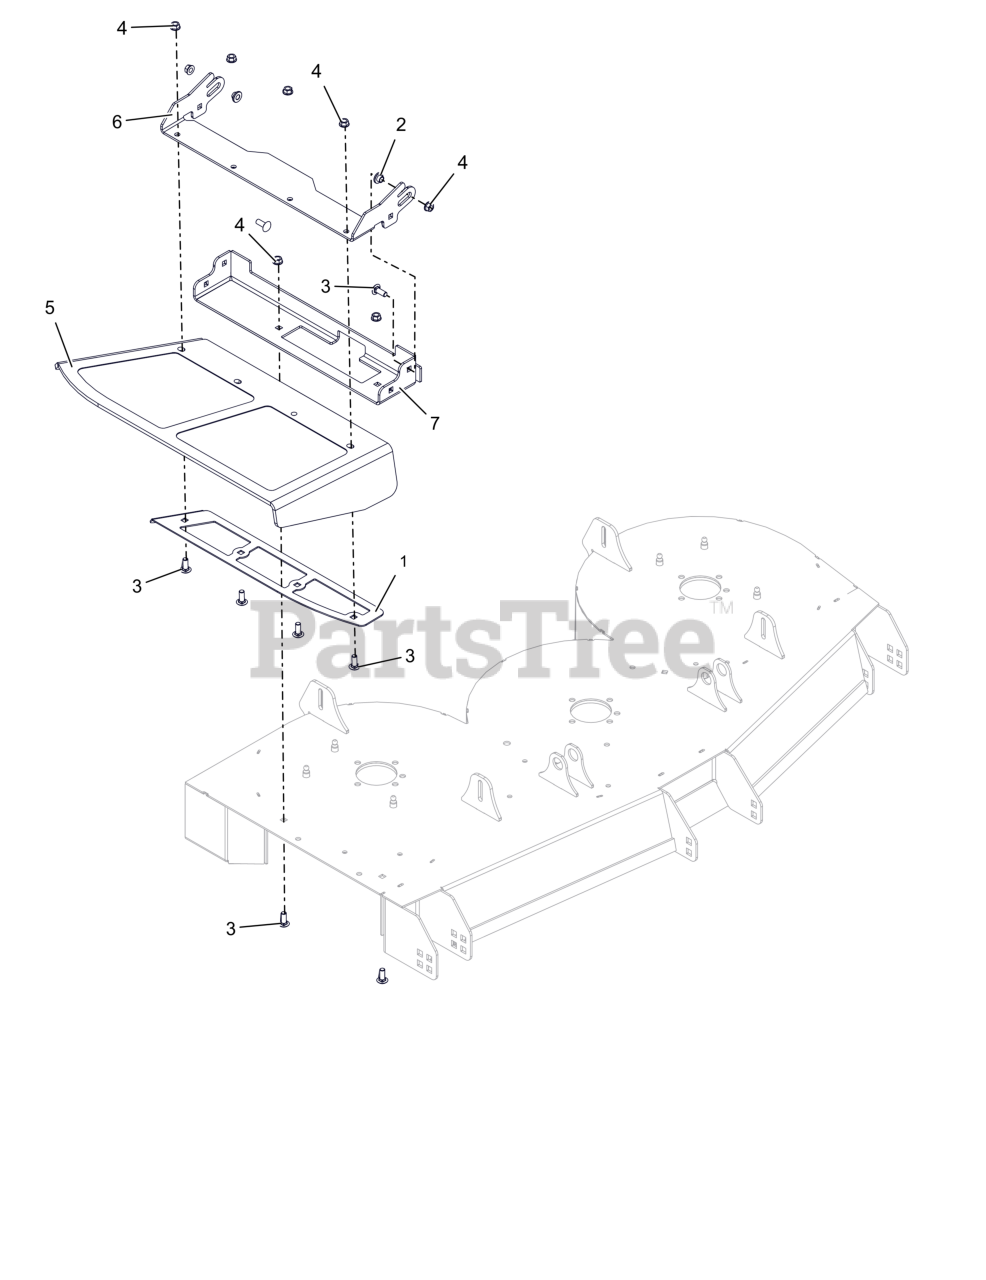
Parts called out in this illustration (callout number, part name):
1	PLATE, DISCH CHUTE CLAMP (BLACK)
2	BSHG-FLG .385X.500X.875X.406
3	BLT,RHSSN .38-16X1.00 G5 ZCC
4	NUT-LK-CTR-FLG .375-16 GF ZCC
5	CHUTE, FORMED RUBBER DISCHARGE
6	BRKT, CHUTE MTG (ORANGE)
7	KIT-DISCH CHUTE LG ORG W/DECAL
